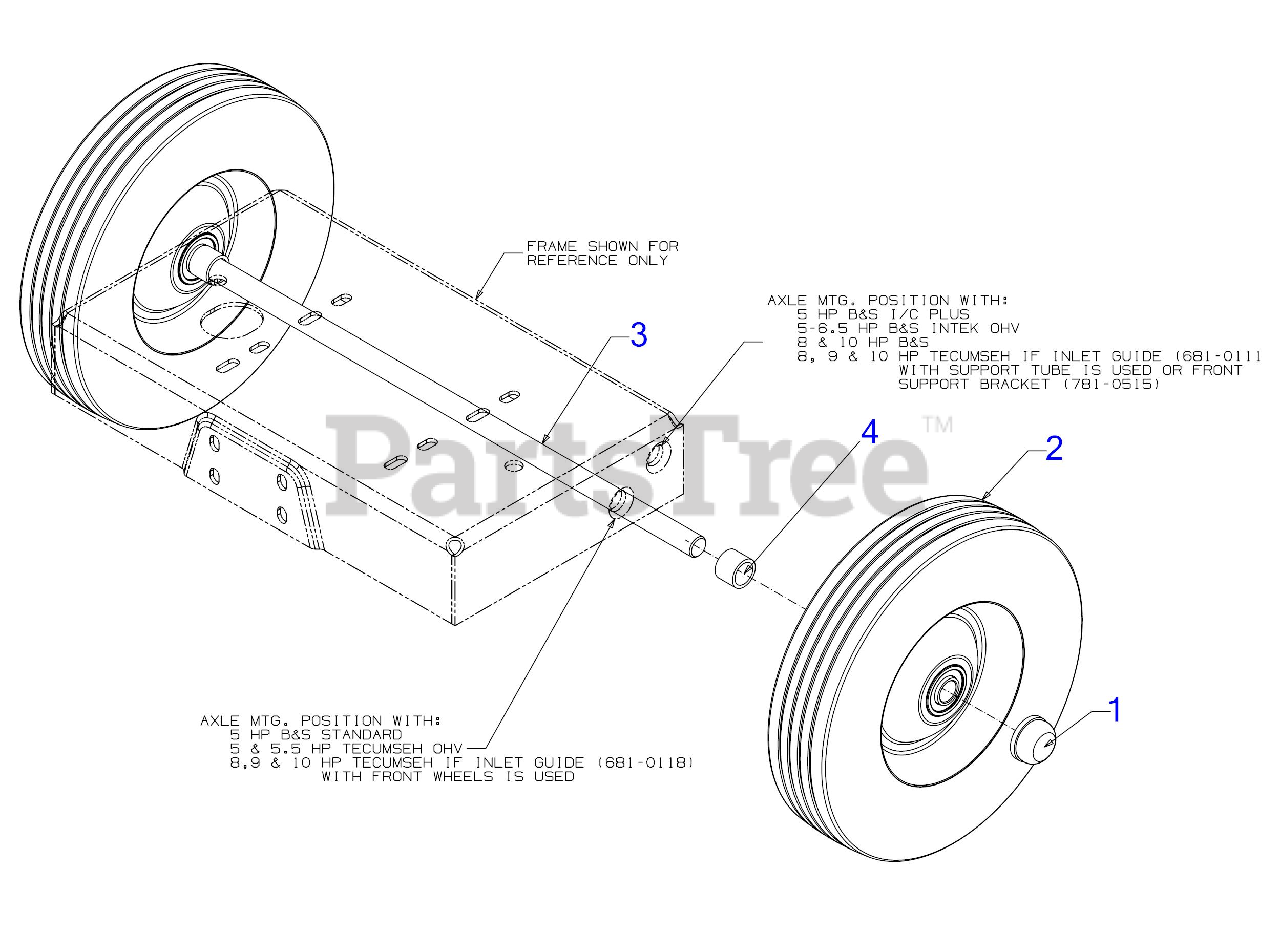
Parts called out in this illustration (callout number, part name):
1	PUSH CAP
2	WHEEL ASM-10" X 2.52 CS
3	SHREDDER AXLE
4	SPACER .666IDX.875ODX.660
